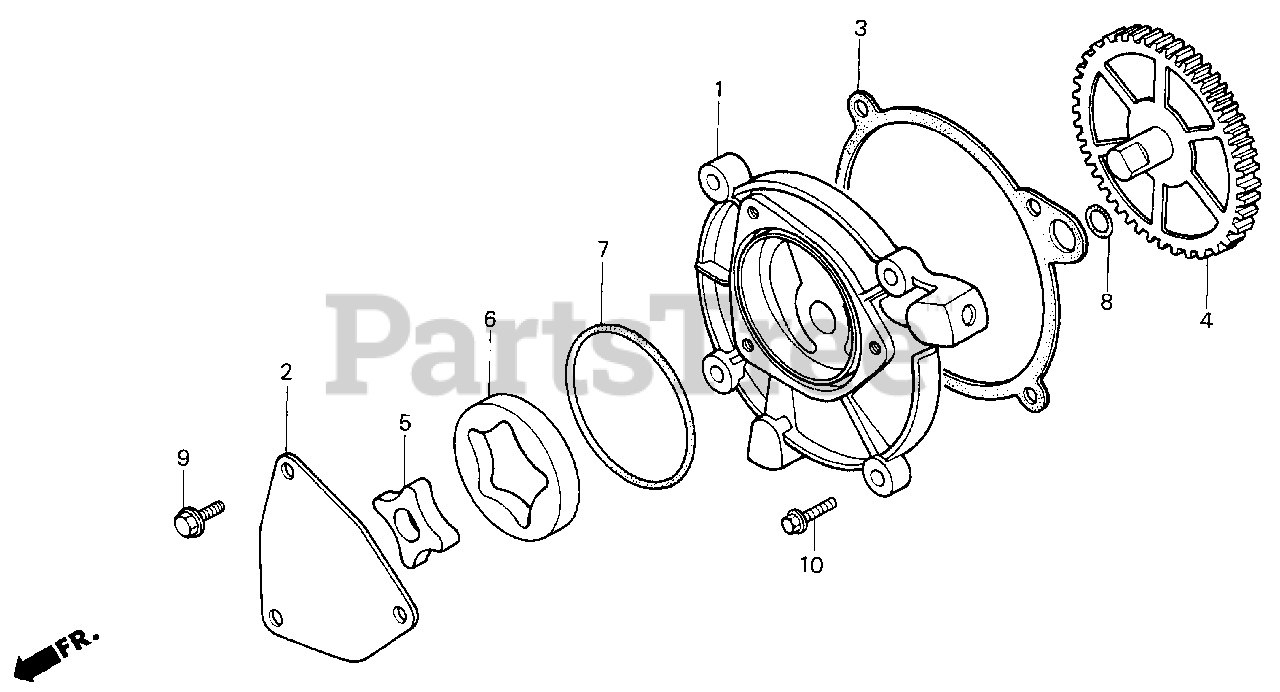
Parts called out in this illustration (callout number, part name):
1	BODY, OIL PUMP
2	COVER, OIL PUMP
3	GASKET, OIL PUMP
4	GEAR ASSY., OIL PUMP
5	ROTOR (INNER)
6	ROTOR (OUTER)
7	O-RING (45X2.5) (ARAI)
7	O-RING, PUMP COVER
8	O-RING (10.8X2.4) (ARAI)
9	BOLT, FLANGE (6X12)
10	BOLT, FLANGE (6X28)
